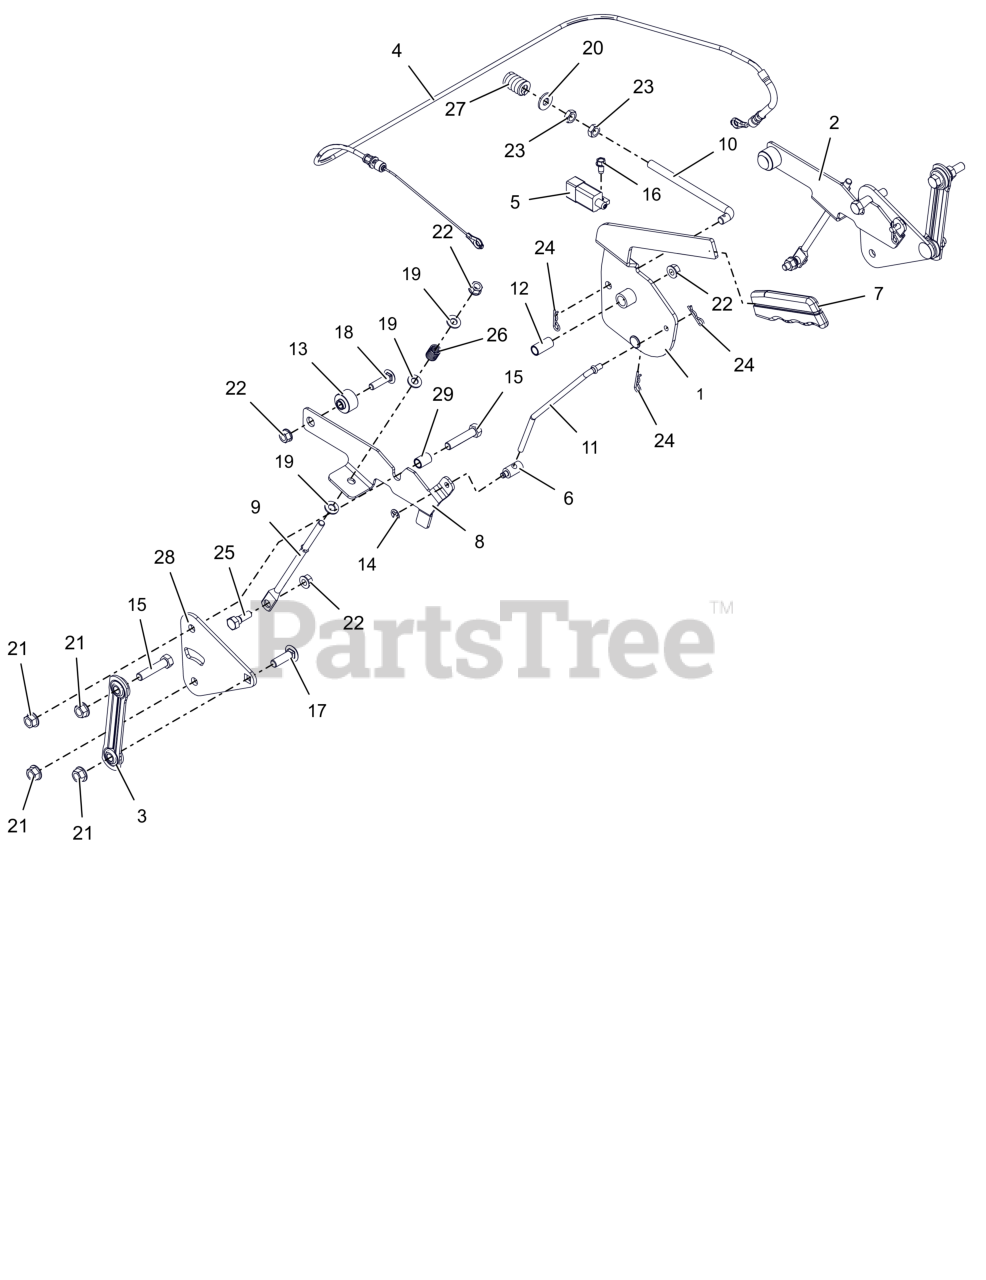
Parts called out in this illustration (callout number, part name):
1	LEVER, PARKING BRAKE
2	ARM, BRAKE - LH (W/PIN)
3	LINK, STAMPED STEERING
4	CABLE, BRAKE - PARKING
5	SWITCH-BRAKE NO/NO-POST & HOLE
6	TRUNION, 1/4-20
7	GRIP, PARKING BRAKE (GREY)
8	ARM, BRAKE - RH
9	ROD, LINK - TRANSMISSION BRAKE
10	ROD, OVER CENTER
11	ROD, BRAKE LINK
12	BSHG-SLV .385X.500X1.045
13	SPCR, FLANGE
14	RG-RTNG-EXT .250X.025
15	BLT, HEX .38-16X1.75 G5 ZCC
16	SCR-TAP .25-20X.50 HWH ZCC
17	BLT,RHSSN .38-16X1.25 G5 ZCC
18	BLT, RHSSN.31-18X1.25 G5 ZCC
19	WSHR,FLT .344X.688X.065 ZCC
20	WSHR,FLT .375X.875X.083 ZCC
21	NUT-LK-TOP-FLG .38-16 ZC120
22	NUT-LK-TOP-FLG .312-18 GF ZCC
23	NUT-JAM .375-16 G2 ZCC
24	PIN, HAIR #213 .08X1.19 ZCC
25	BOLT,SHLDR .38X.25 -.31-18X.75
26	SPRING, COMPRESSION
27	SG-COMP .187X.56X1.62
28	PLATE, TRANSAXLE (BLACK)
29	SPCR SLEEVED .385X.500X.718
